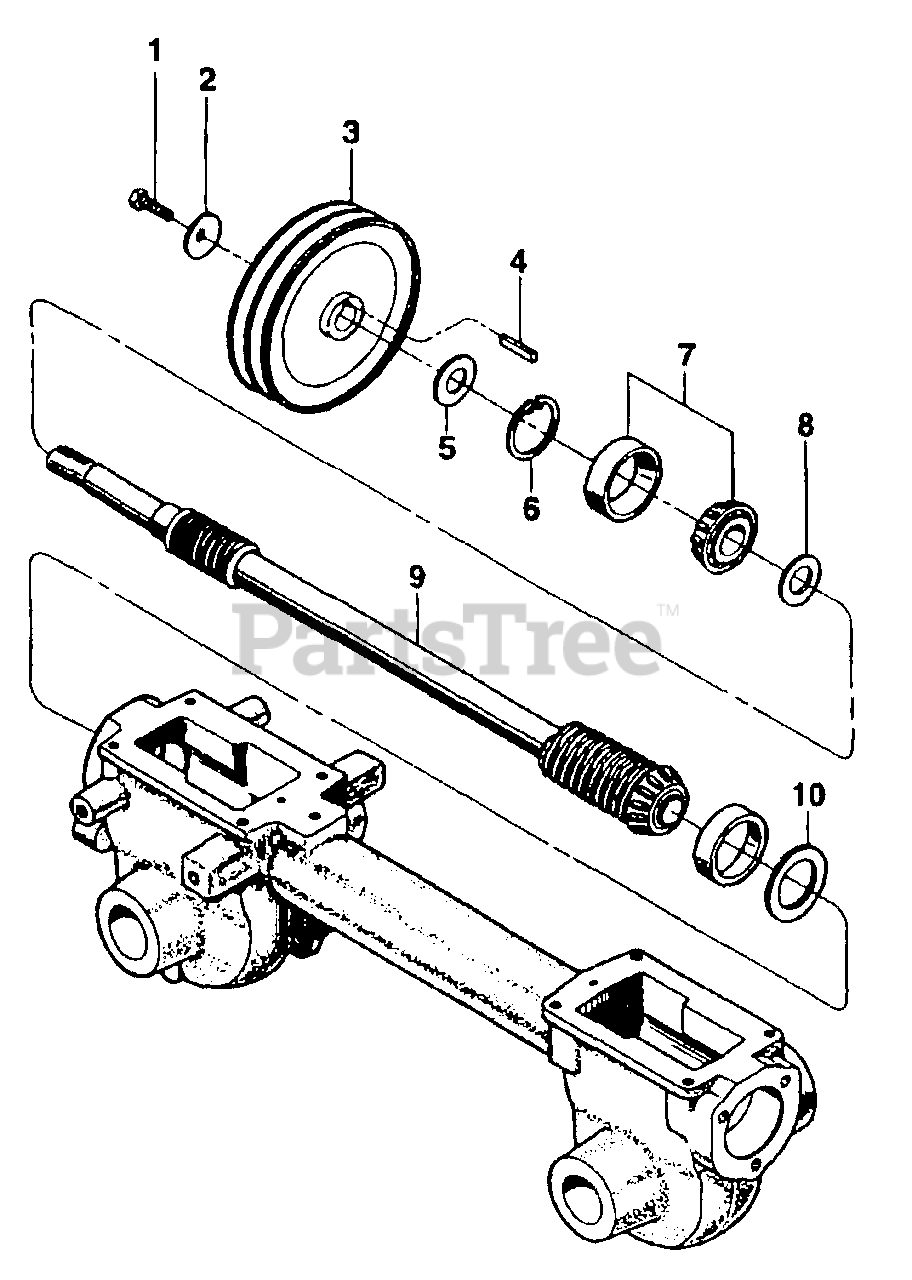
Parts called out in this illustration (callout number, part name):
1	Hex Screw, 5/16-24 x 1, Grade 5
2	Washer, Belleville
3	Pulley, Transmission
4	Key-Transmission Pulley, 3/16 x 1
5	Support Washer, Front
6	Snap Ring
7	Bearing, Tapered Roller (with race).
8	Support Washer, Rear
9	Drive Shaft Assembly
10	Shim, Rear Bearing Cap, .010 thick
